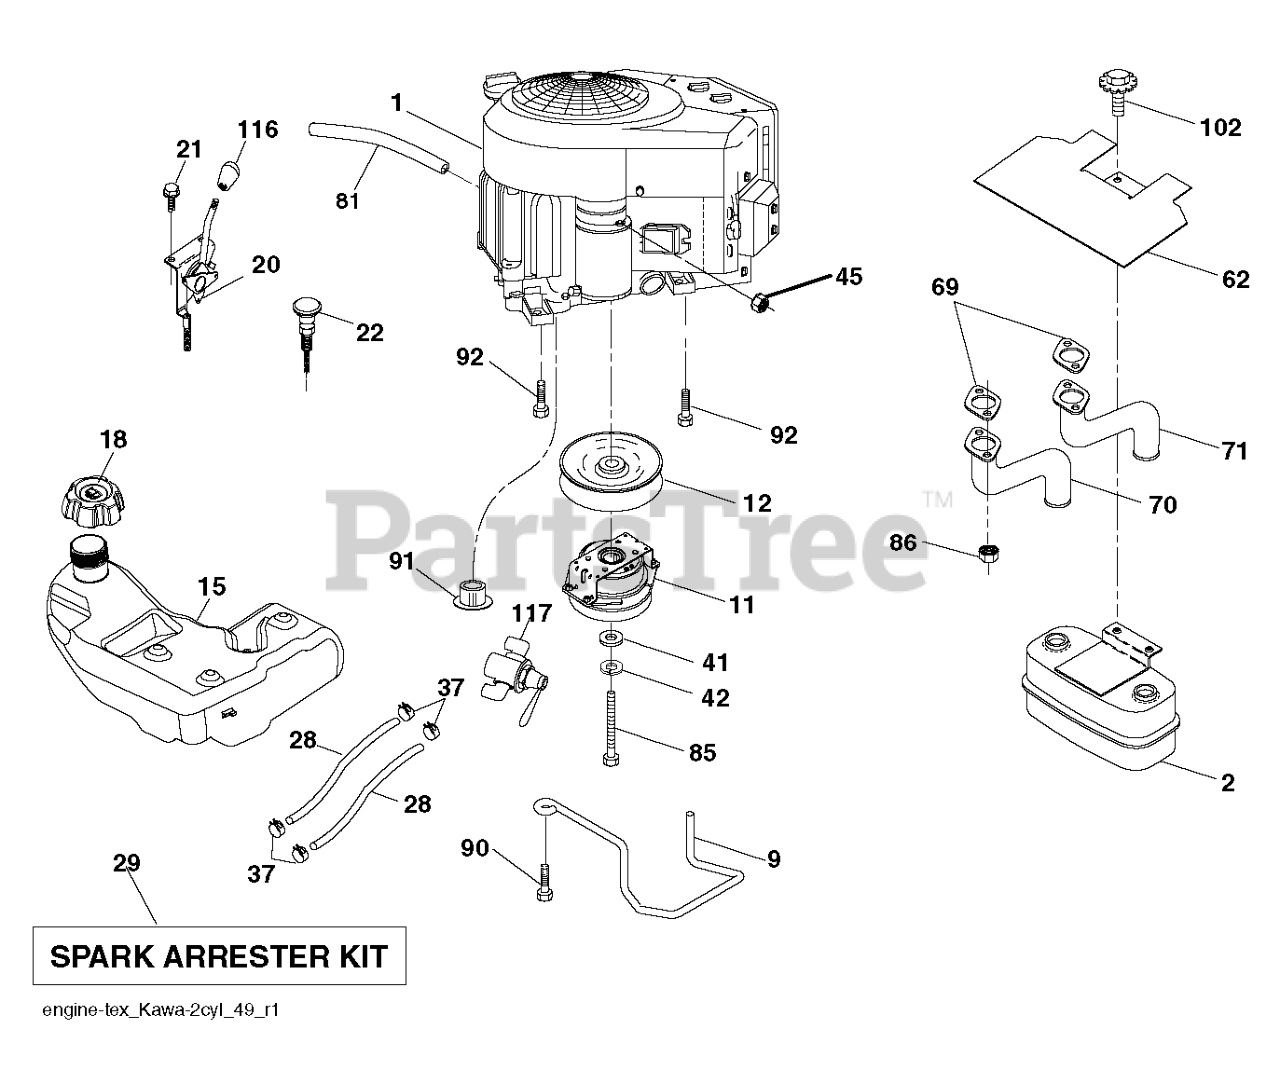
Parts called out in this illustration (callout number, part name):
2	MUFFLER.ASM.TWIN.MNTG.BRACKET
9	KEEPER BELT ENGINE
11	CLUTCH.OGURA.5.0PD.GT1.5A-EH01
12	PULLEY ENGINE
15	TANK.ASM.FUEL.4R.GAL.EPA.17
18	FUEL CAP
18	CAP ASSY FUEL 3" GRAY
20	CONTROL.THROTTLE.PRO.
21	SCREW.#10 X 0.750.BOS
22	CONTROL.CHOKE.ERGO.PUSH-IN.BLA
28	LINE.FUEL.64"REAR.EMIS
29	KIT.SPARK ARRESTOR 794945 B&S
37	HOSE CLAMP
42	LOCKWASHER
45	NUT
62	SHIELD.HEAT.MUFFLER
70	TUBE.EXHAUST.LH.FR961/FR730
71	TUBE.EXHAUST.RH.FR961/FR730
81	TUBE, DRAIN OIL ASM.
85	BOLT.HEX.7/16-20X3.0XGR5
86	NUT.HEX.FLANGE.TOPLOCK
90	SCREW 3/8-16X1
91	BUSHING.1.375OD
92	SCREW 3/8-16X1
102	SCREW
116	RP KNOB SOFT TOUCH
117	VALVE FUEL RESERVE
